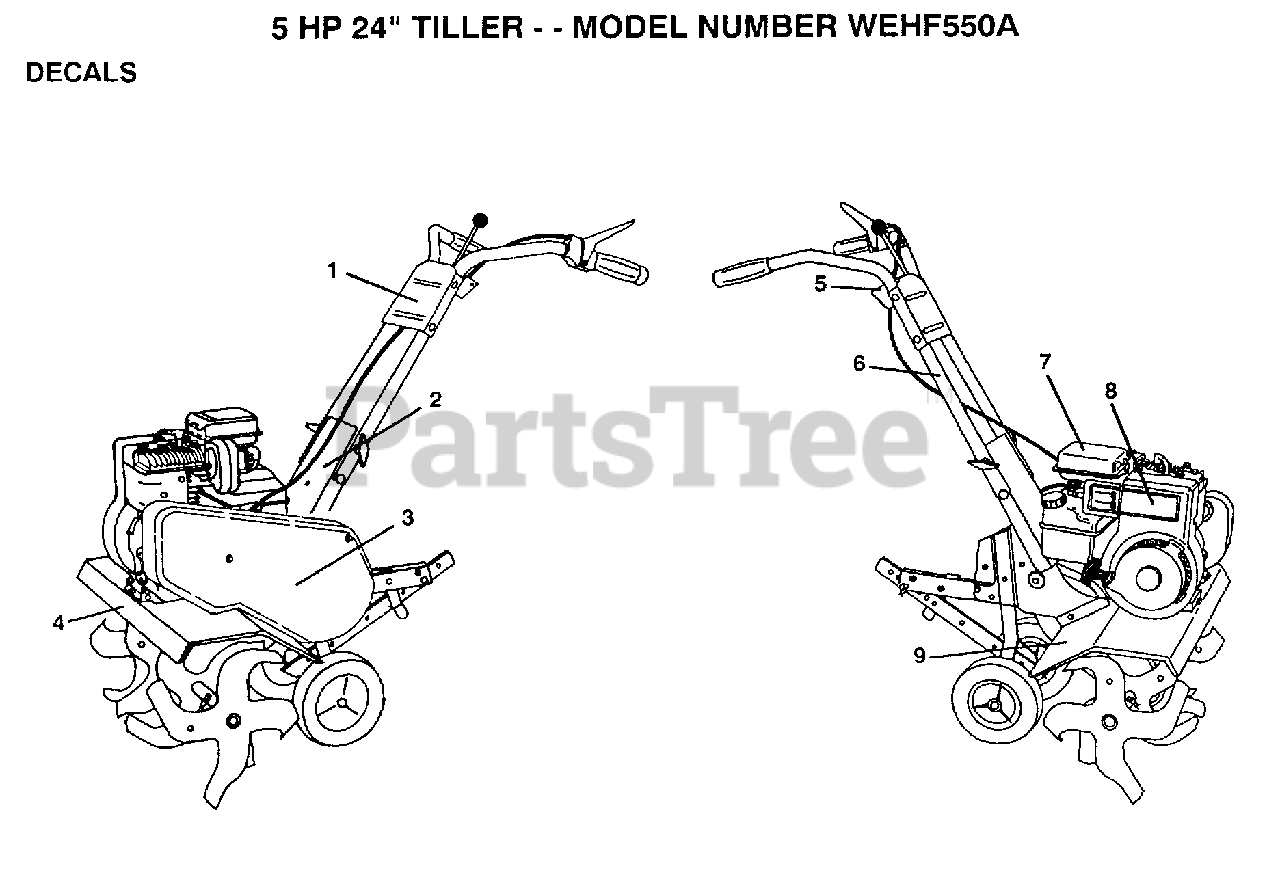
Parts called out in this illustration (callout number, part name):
2	DECAL.PNL.HANDLE
3	DECAL GUARD BELT
4	DECAL.SHIELD.TINE
5	DECAL REVERSE
6	DECAL TI
7	DECAL TI
